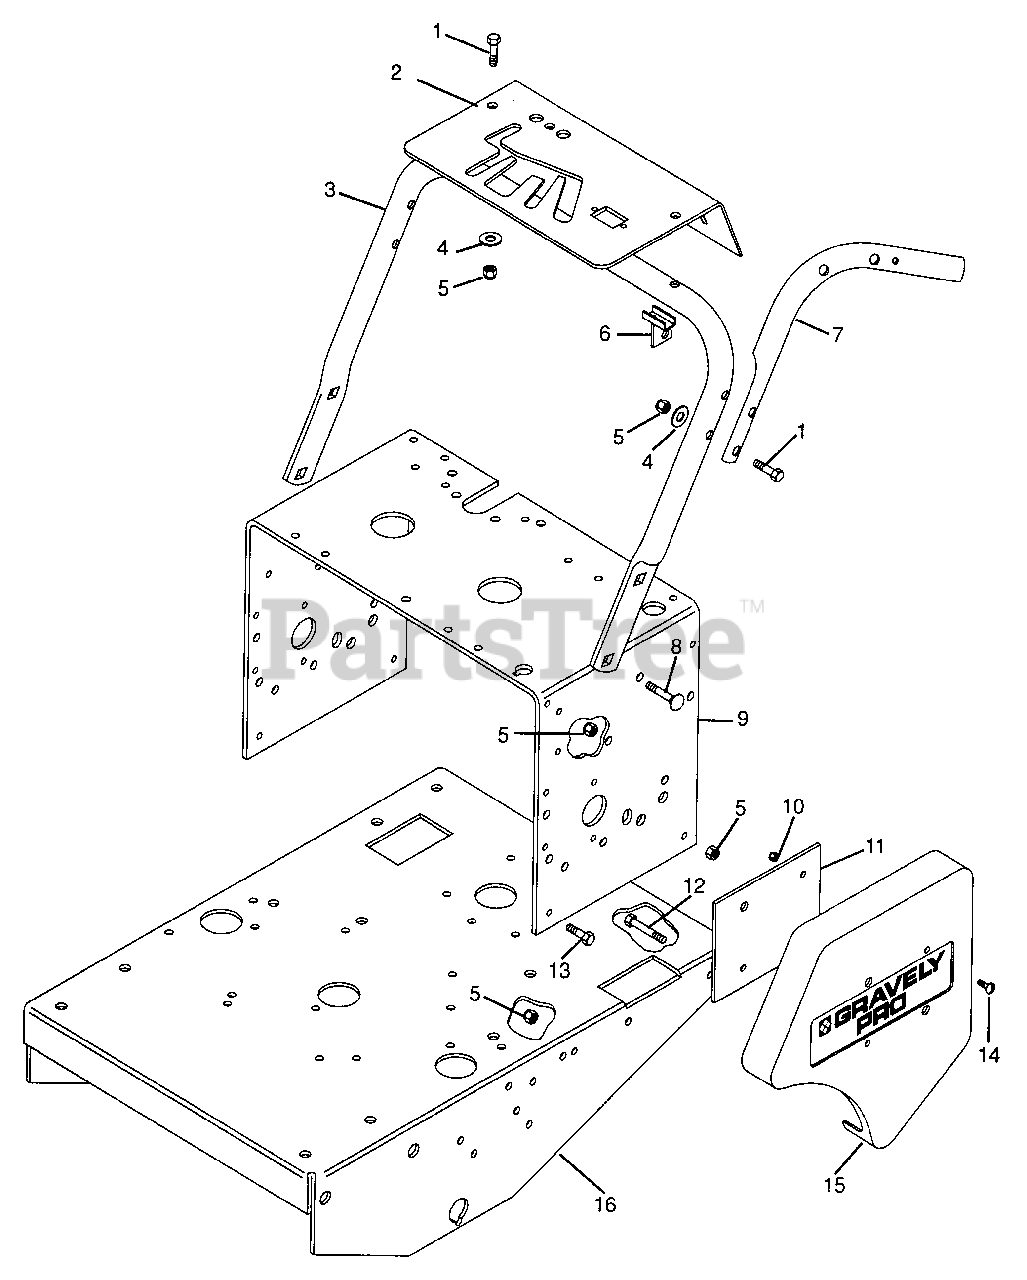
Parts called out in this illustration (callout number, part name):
1	Bolt-Hex .38-16 x 2.00 Grade 5
2	Panel, Instrument
3	Tube, Handlebar Mounting
4	Washer-Flat-Steel .406 x .812 x .065
5	Nut-Locking-Nylon .375-16 Grade 2
6	Weldment, PTO Lever Mounting
7	Handlebar Left Hand
7	Handlebar Right Hand
8	Bolt-Round Head Square Neck .38-16 x 1.0
9	Support, Handlebar
10	Nut-Locking-Center.250-20 Grade 2
11	Bracket, Belt Guard Left Hand
12	Bolt-Hex .38-16 x 1.25
13	Bolt-Hex .38-16 x 1.00 Grade 5
14	Screw-Machine .25-20 x .75
15	Guard, Belt Left Hand
15	Guard, Belt Right Hand
16	Weldment, Pro Frame
